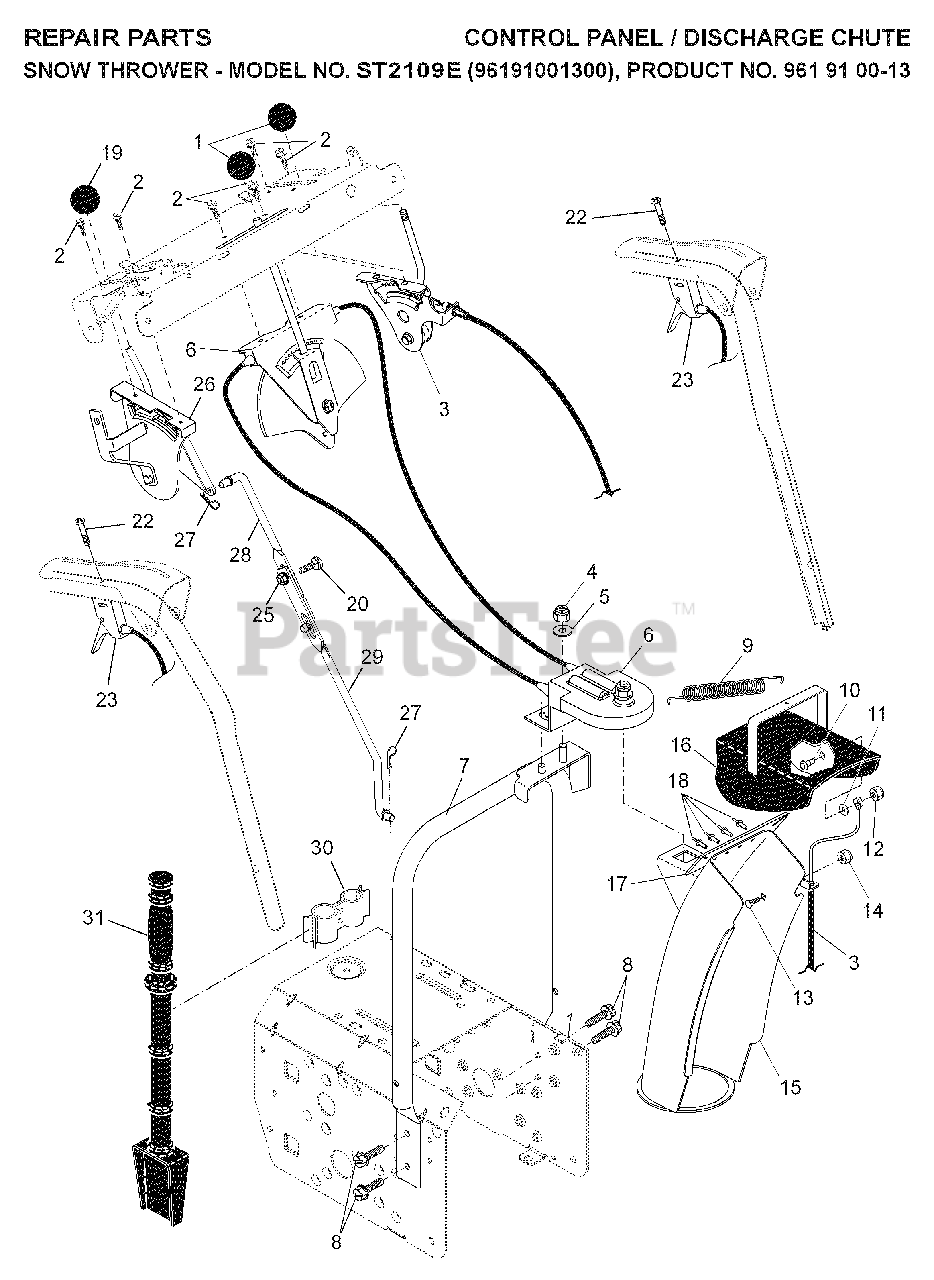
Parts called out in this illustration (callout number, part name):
1	KNOB, LEVER
2	SCREW #10-24 X 5/8
3	CONTROL.CABLE.DEFLECTOR
4	NUT
6	CONTROL.CABLE.CHUTE.RO
7	SUPPORT, PIVOT
8	SELF-TAPPING SCREW 5/16-18X3/4
10	BOLT, SHOULDER
11	WASHER, NYLON FRICTION
12	LOCKNUT
13	BOLT
14	NUT, LOCK 5/16-18
17	SEAL, DEFLECTOR
18	RIVET BLIND
19	RP KNOB, SPEED CONTROL LEVER
23	STEERING.CONTROL.SNOW THROWER
25	NUT, HEX FLANGE 5/16-18
26	HEAD ASSY SPEED
27	SPRING RETAINER
28	ROD, UPPER SPEED CONTROL
29	ROD, LOWER SPEED CONTROL
30	CLAMP.ASM.CLEANOUT.TOOL.SNOW
31	CLEAN OUT TOOL
